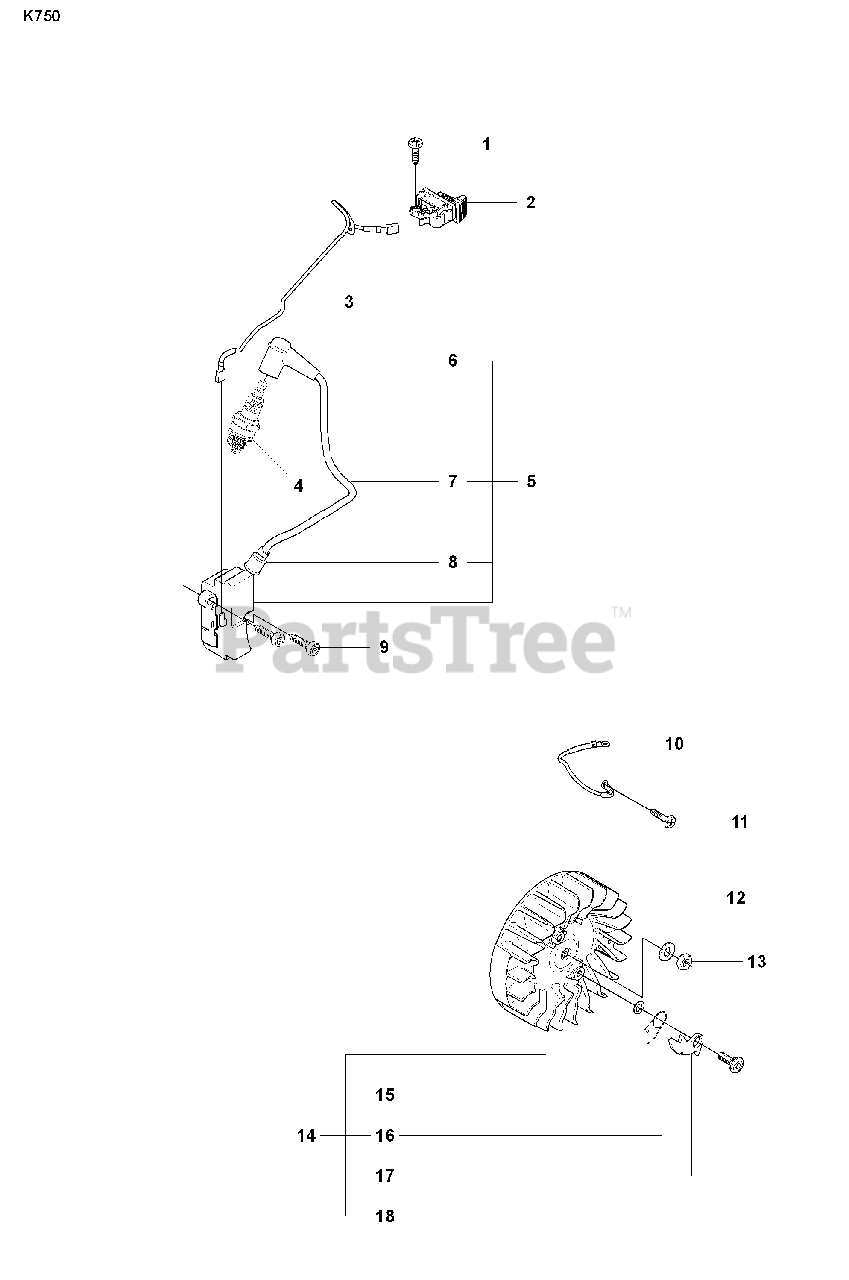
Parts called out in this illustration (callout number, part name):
2	STOP SWITCH
3	CABLE
4	SPARK PLUG
5	IGNITION MODULE
6	SPARK PLUG CAP
7	IGNITION CABLE
8	INSULATING CUP
12	WASHER STEEL
14	FLYWHEEL
15	WASHER STEEL
